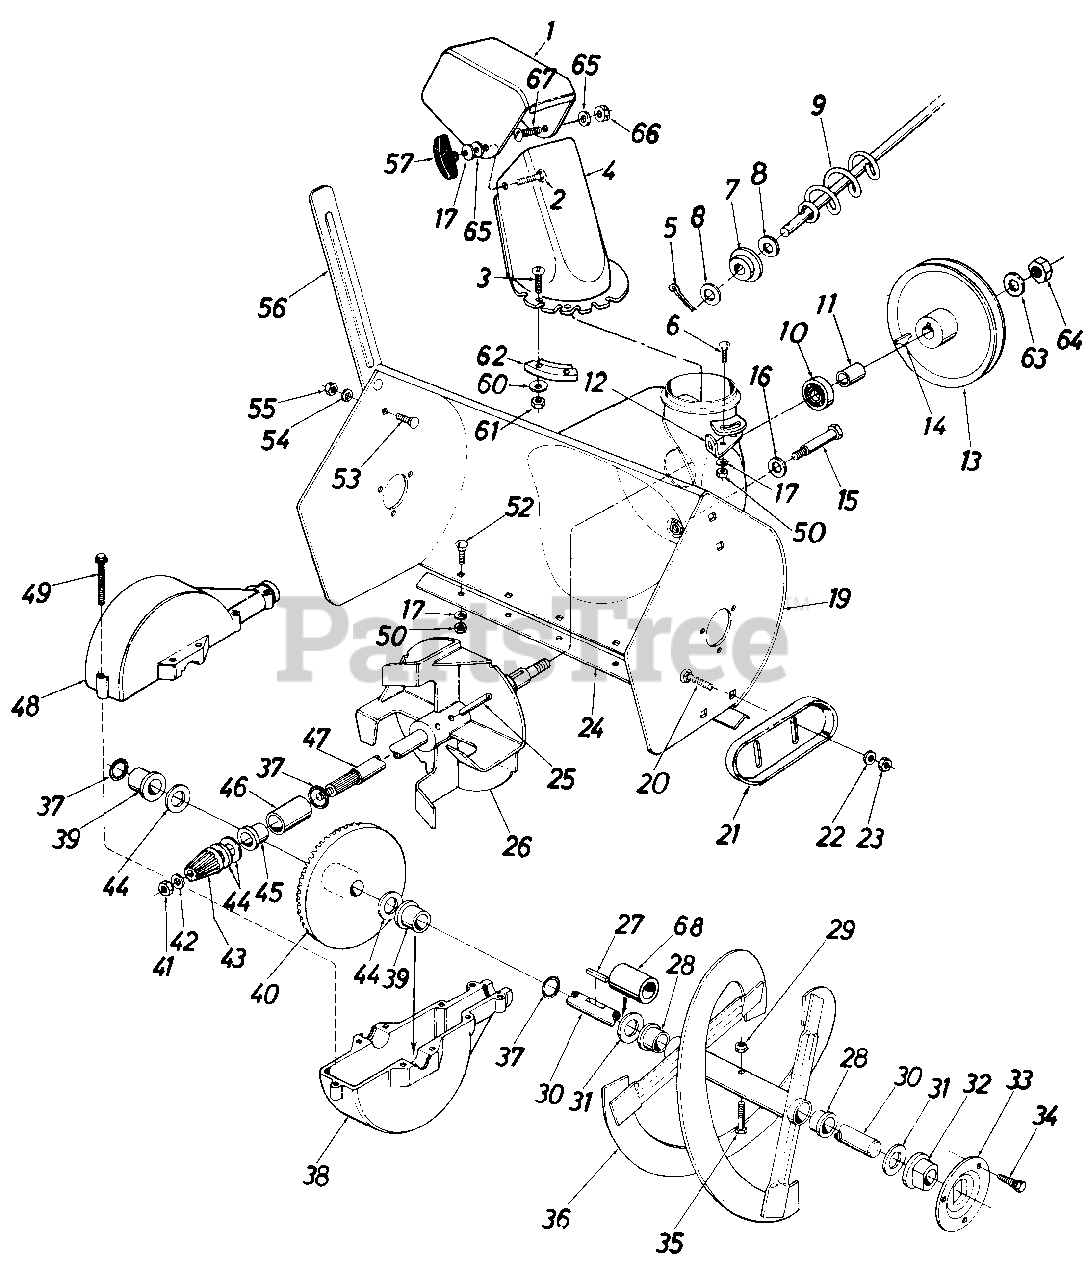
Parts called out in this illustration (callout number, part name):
1	Upper Chute
2	Carriage Bolt 5/16-18 x 1.0"
3	Truss Mach. Scr. 1/4-20 x .75
4	Lower Chute
5	Cotter Pin
6	Carriage Bolt 5/16-18 x .75"*
7	Bushing
8	Fl-Wash. .385 I.D. x .62" O.D.
9	Chute Crank Ass'y.
10	Ball Brg. .62" I.D. x 1.38" O.D.
11	Spacer .63" I.D. x .88" O.D. x . 900 " Lg .
13	1/2" 'V"-Pulley .625" I.D. x 7.50" O.D. (420 & 524)
14	#61 Hi-Pro Key 3/16" x 5/8" Dia
15	Shld. Bolt .50" Dia. x 2.11"
16	Bell-Wash. .40" I.D. x .88" O.D. x .06
17	Bell-Wash. .34" I.D. x .88" O.D.
20	Carriage Bolt 3/8-16 x .62"
21	Slide Shoe
22	Bell-Wash. 3/8" I.D.
23	Hex Jam Nut 3/8-16 Thd.
24	20" Shave Plate (420)
26	11" Dia. Blower Fan Ass'y.
27	Sq. Key 3/16" x 1.5" Lg.
28	Flange Brg. .75" I.D. x .88" O.D.
29	Hex Ins. L-Nut 5/16-18
30	Spiral Axle (420)
31	Fl-Wash. .75" I.D. x 1.50" O.D. x .06
32	Flange Brg. w/Flats .755" I.D.
33	Bearing Housing
34	Hex Wash. Hd. Self-Tap Scr.5/16-24 x .62" Lg.
35	Hex Bolt 5/16-18 x 1.50" Lg.
36	20" Spiral Ass'y.-L.H. (420)
37	"O"-Ring-314" I.D.
38	Bevel Gear Housing-Lower Half
39	Plastic Flange Brg. .755" I.D.
40	Bevel Gear
41	Hex Cent. L-Nut 5/16-24 Thd.
42	Fl-Wash. .34" I.D. x .62" O.D. x .06
43	Pinion Gear
44	Fl-Wash. .75" I.D. x 1.25" O.D. x .06
45	Flange Brg. .755" I.D.
46	Sleeve Brg. .755" I.D.
47	Blower Axle
48	Bevel Gear Housing- Upper Half
49	Hex Wash. Hd. Self-Tap Scr. 1/4-20 x 1.00" Lg.
50	Hex Nut 5/16-18 Thd.*
52	Carriage Bolt 5/16-18 x .62" Lg.*
53	Carriage Bolt 5/16-18 x .62" Lg *
54	L-Wash. 5/16" I.D.*
55	Hex Nut 5/16-18 Thd *
56	Drift Cutter Bar
57	Knob
60	Fl-Wash. 1/4" I.D.
61	Hex L-Nut 1/4-20 Thd.*
62	Chute Flange Keeper
63	Fl-Wash. .64" I.D. x .94" O.D. x .06
64	Hex Jam Nut 5/8-18 Thd.
65	Fl-Wash. .344 I.D. x 1.125 O.D.
66	Hex L-Nut 5/16-18 Thd.
67	Truss Mach. Scr. 5/16-18 x .75" Lg.
68	Spacer (826)
